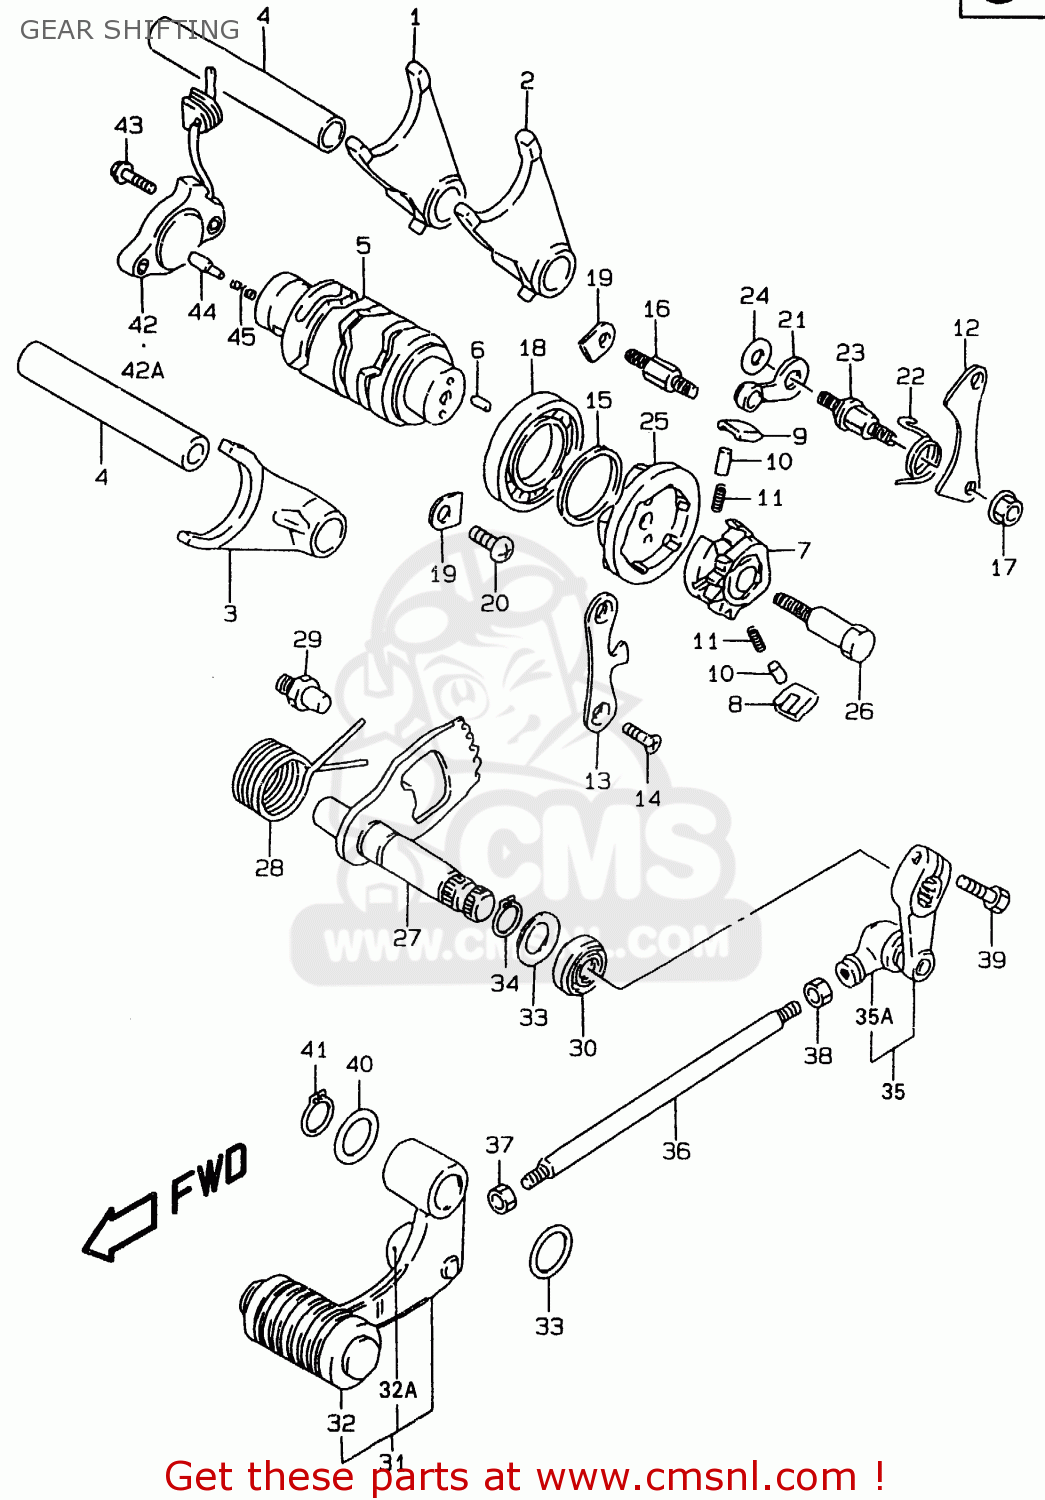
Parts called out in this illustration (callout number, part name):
1	FORK,GEAR SHIFT NO.1
2	FORK,GEAR SHIFT NO.2
3	FORK,GEAR SHIFT NO.3
4	SHAFT,GEAR SHIFT FORK
5	CAM,GEAR SHIFT
6	PIN
7	GEAR,GEARSHIFT CAM DRIVE
8	PAWL,GEAR SHIFT NO.1
9	PAWL,GEAR SHIFT NO.2
10	PIN(5X8)
11	SPRING
12	LIFTER,GEAR SHIFT POLE
13	GUIDE,GEAR SHIFT CAM
14	SCREW
15	WASHER(25X32X3)
16	BOSS,SHIFT PAWL LIFTER
17	NUT
18	BEARING(25X47X8)
19	RETAINER
20	SCREW
21	STOPPER,GEAR SHIFT CAM
22	SPRING
23	SUPPORT,CAM STOPPER ARM
24	WASHER
25	PLATE,GEAR SHIFT CAM
26	PIN,SHIFT CAM DRIVEN GEAR
27	SHAFT,GEAR SHIFT
28	SPRING
29	STOPPER,GEAR SHIFT CAM
30	OIL SEAL
31	LEVER ASSY,GEAR SHIFT
32	RUBBER,GEAR SHIFT PEDAL
32A	COVER,DUST
33	WASHER(12.5X20X1)
34	CIRCLIP,12 MM
35	ARM,GEAR SHIFT LINK
35A	COVER,DUST
36	ROD,GEAR SHIFT LINK
37	NUT
38	NUT 6MM
39	BOLT
40	WASHER
41	CIRCLIP,12 MM
42	BASE ASSY,GEAR SHIFT TERMINAL
42A	BASE ASSY,NEUTRAL SW TERMINAL
43	SCREW
44	PIN(5X15.5)
45	SPRING
